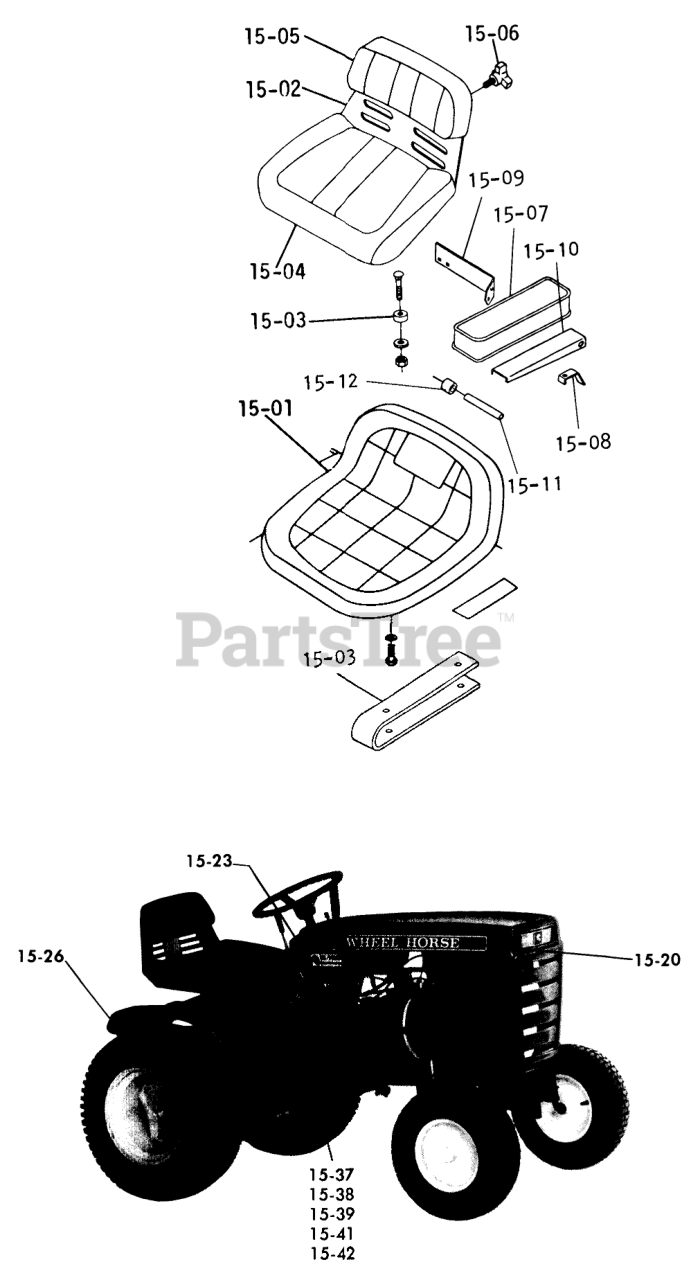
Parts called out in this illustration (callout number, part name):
15-01	Seat
15-02	Seat Base Assy.
15-03	Spring
15-04	Cushion Seat
15-05	Back Cushion
15-06	Knob 8 HP
15-07	Arm Rest Pad
15-08	Arm Stop
15-09	Bracket-R.H.
15-11	Spacer
15-12	Spacer
15-20	Decal
15-23	DECAL C 160
15-23	Decal
15-23	Decal-B-100 Automatic
15-26	Reflector
15-37	Lockwasher
15-38	Decal-Maintenance
15-39	Decal-Read Manual
15-41	DECAL PTO SPD. CONT
15-42	DECAL-HAND LIFT
15-42	Washer
